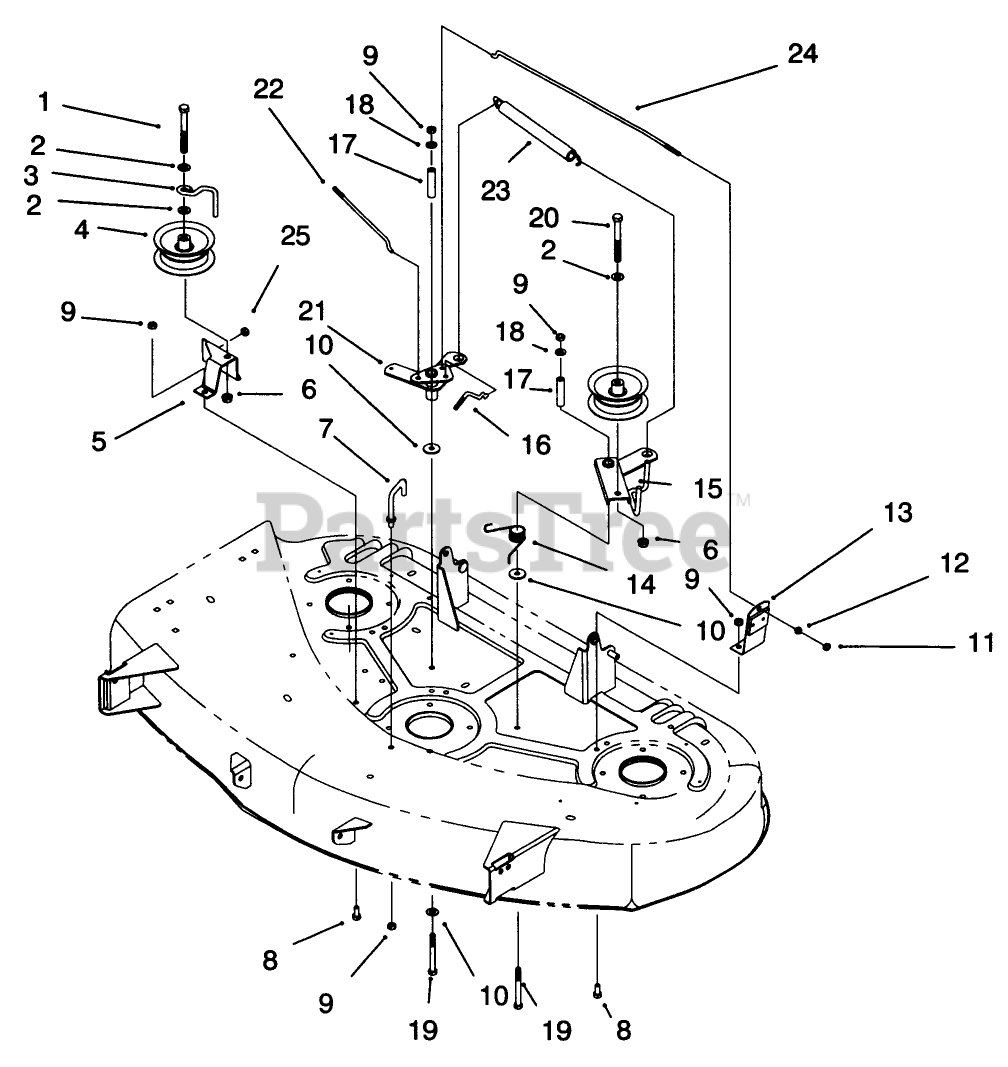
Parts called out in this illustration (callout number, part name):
1	SCREW-HH
2	WASHER-FLAT
3	GUIDE-IDLER, BELT
4	PULLEY-IDLER, FLAT
5	Bracket-Idler
6	NUT-LOCK, NI
7	GUIDE-TRANS BELT, LH
8	SCREW-HH
9	NUT-LOCK, NI
10	WASHER-PIVOT
11	NUT-LOCK, NI
12	BALL-SWIVEL, STOP
13	BRAKE ASM
14	SPRING-TORSION
15	Bellcrank
16	ROD-BRAKE, CENTER
17	Spacer-Pivot
18	WASHER-PLAIN
19	SCREW-HH
20	SCREW-HH
21	Bellcrank
22	ROD-BRAKE, RH
23	SPRING-ENGAGE, DECK
24	ROD-BRAKE, LH
25	NUT-JAM
